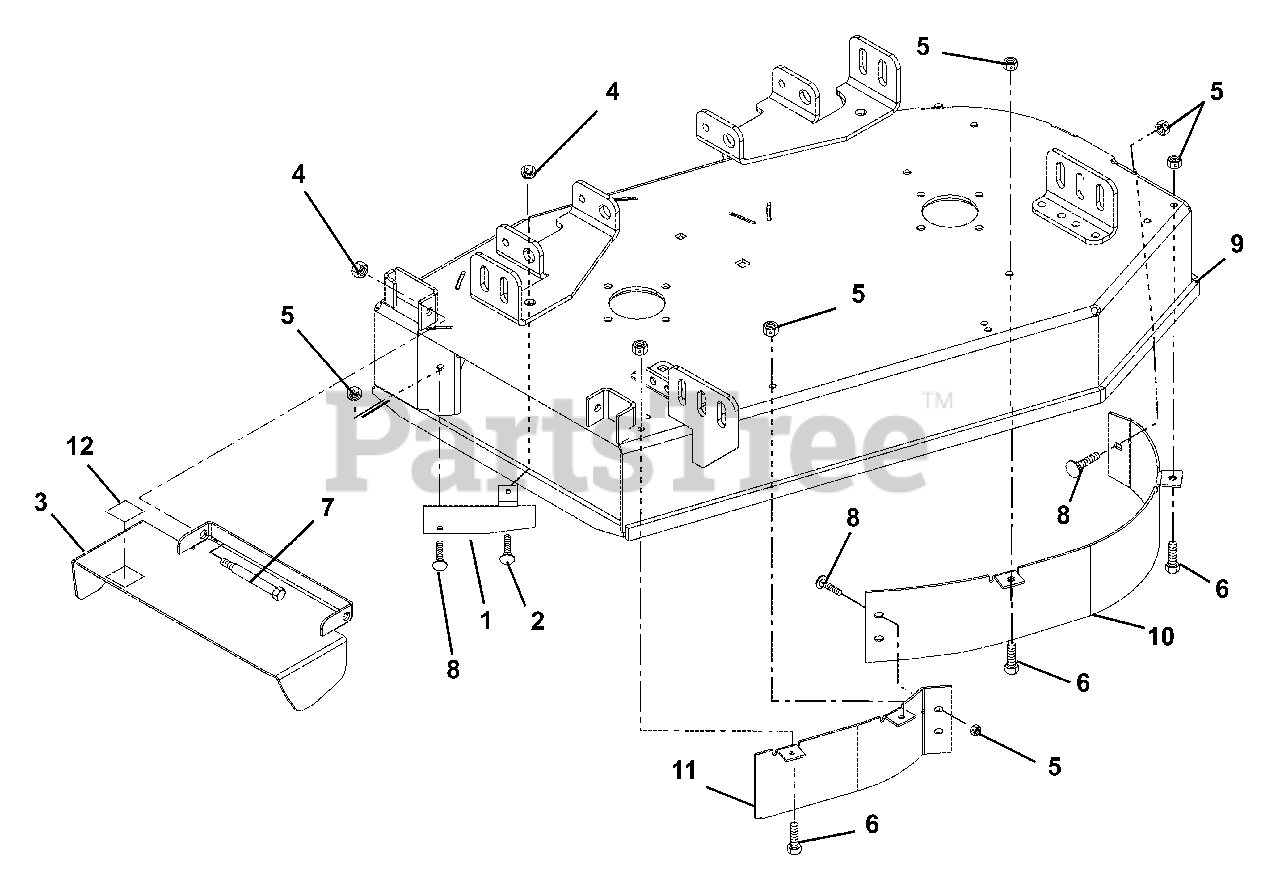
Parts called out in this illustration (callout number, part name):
1	Baffle, Deflector
2	Bolt-Round Head Square Neck .38-16 x 1.00 Grade 5
3	Chute, Discharge CE (314)
3	Chute, Discharge (056)
4	Nut-Locking-Top-Flange .38-16
5	Nut-Locking-Top-Flange .31-18
6	Bolt-Hex .31-18 x .75 Grade 5
7	Bolt-Shoulder .38-16 x .50 Socket Head
8	Bolt-Round Head Square Neck .31-18 x .75 Grade 5
9	Weldment, 34" Deck
10	Baffle, 34" Front Left Hand
11	Baffle, 34" Front Right Hand
12	Grip, Pedal 1.50 x 3.00
